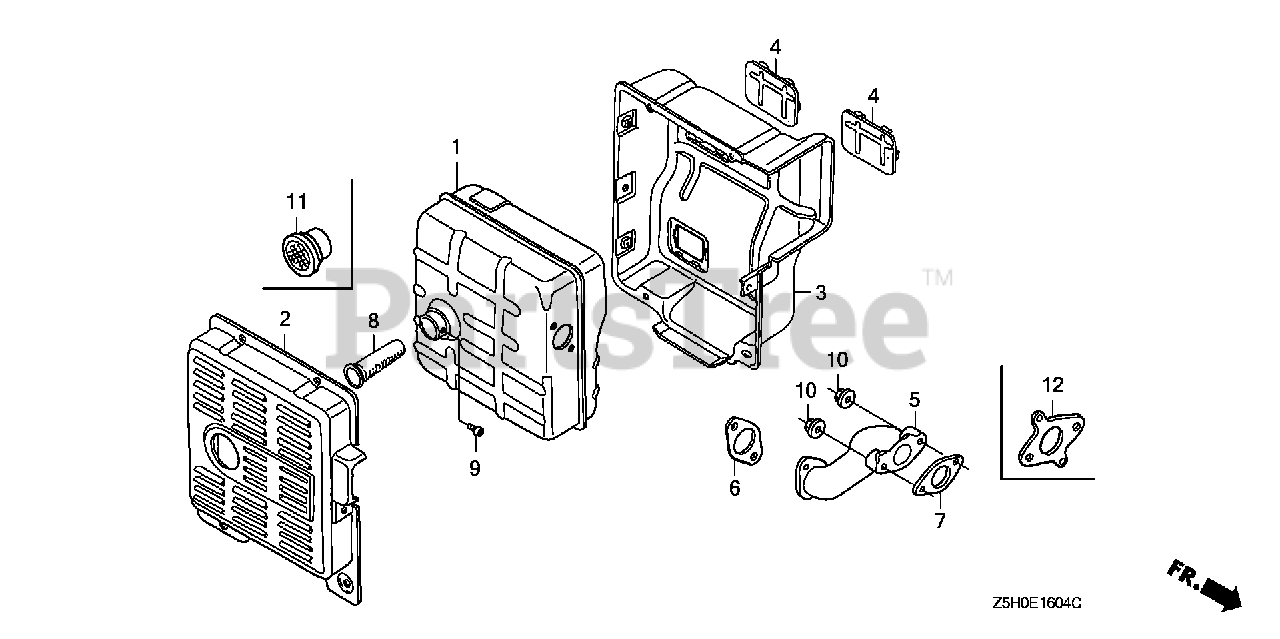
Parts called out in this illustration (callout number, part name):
1	MUFFLER (TSURUMI)
2	PROTECTOR, MUFFLER (OUTER)
3	PROTECTOR, MUFFLER (INNER)
4	SEAL, MUFFLER PROTECTOR
6	GASKET, EX. PIPE
7	GASKET, EX. PIPE
8	ARRESTER, SPARK
9	SCREW, TAPPING (4X8)
9	SCREW, TAPPING (4X6)
10	NUT, FLANGE (8MM)
11	NETTING, WIRE FLANGE
12	GASKET, EX. PIPE
